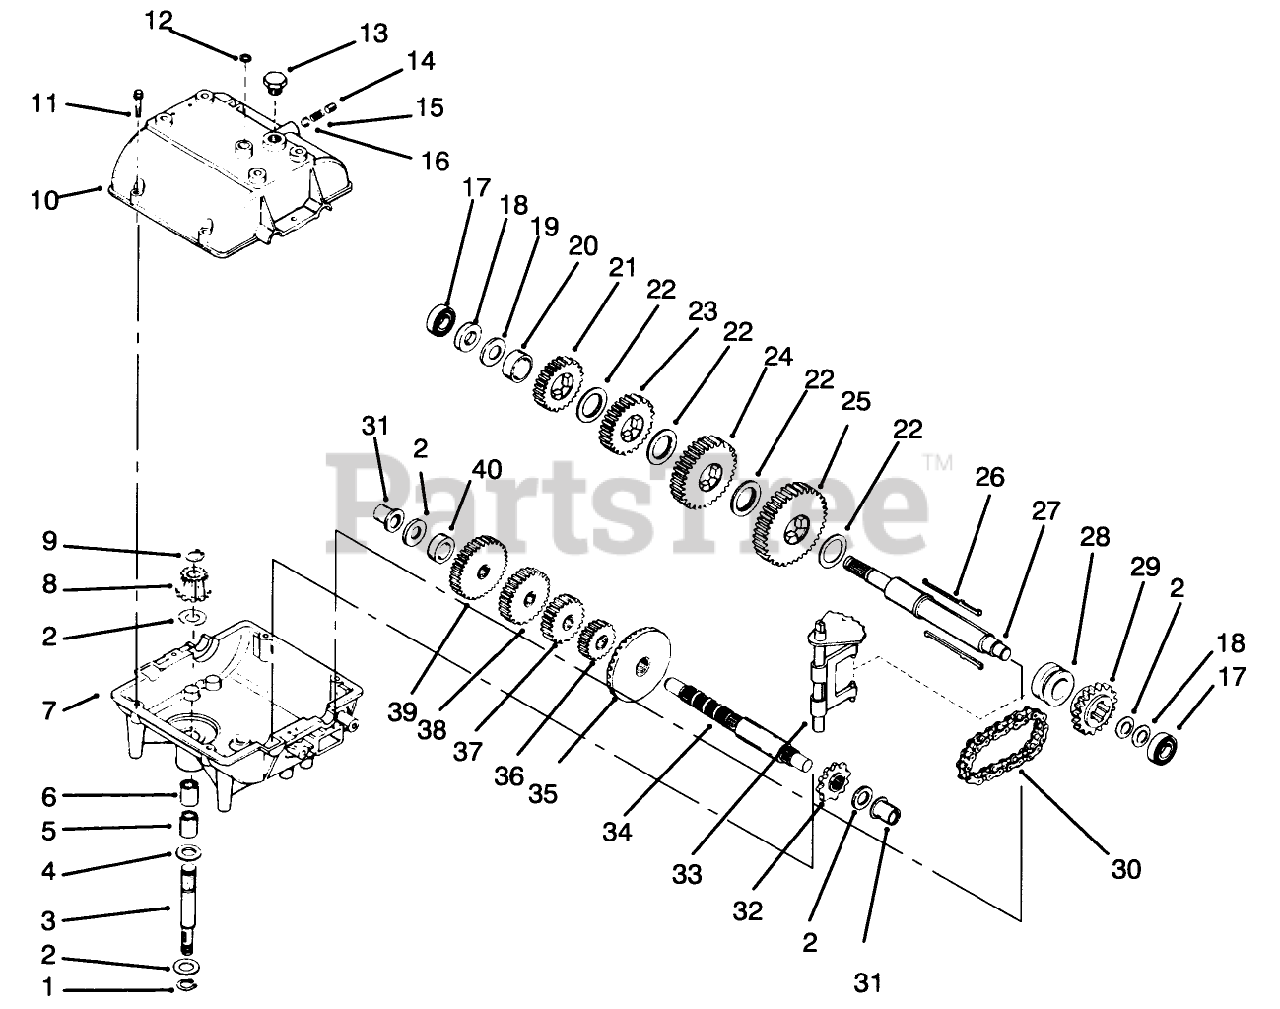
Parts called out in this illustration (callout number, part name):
1	Ring-Snap
2	Washer
3	Shaft-Input
4	O Ring
5	Bearing-Needle
6	Bearing-Needle
7	Case-Transmission
8	Bevel Pinion-Input
9	Ring-Retainer
10	Cover-Transmission
11	Ring Set (.020 O S)
12	Cut Seal-Square
14	Screw-Set
15	Spring
16	Ball-Steel
17	Bearing-Ball
18	Thrust Washer
19	Washer
20	Spacer
21	Gear-Spur, 25 Teeth
22	Washer
23	Gear-Spur 27 Teeth
24	Gear-Spur, 30 Teeth
25	Gear-Spur, 35 Teeth
27	Shaft-Output/Brake
28	Collar-Shift
29	Sprocket-18 Teeth
30	Chain-Roller #41
31	Bushing-Flange
32	Sprocket-9 Teeth
33	Rod and Fork ASM
34	Countershaft
35	Gear-Bevel, 42 teeth
36	Gear-Spur 15 Teeth
37	Gear-Spur, 20 Teeth
38	Gear-Spur 23 Teeth
39	Gear-Spur, 25 Teeth
40	Spacer
